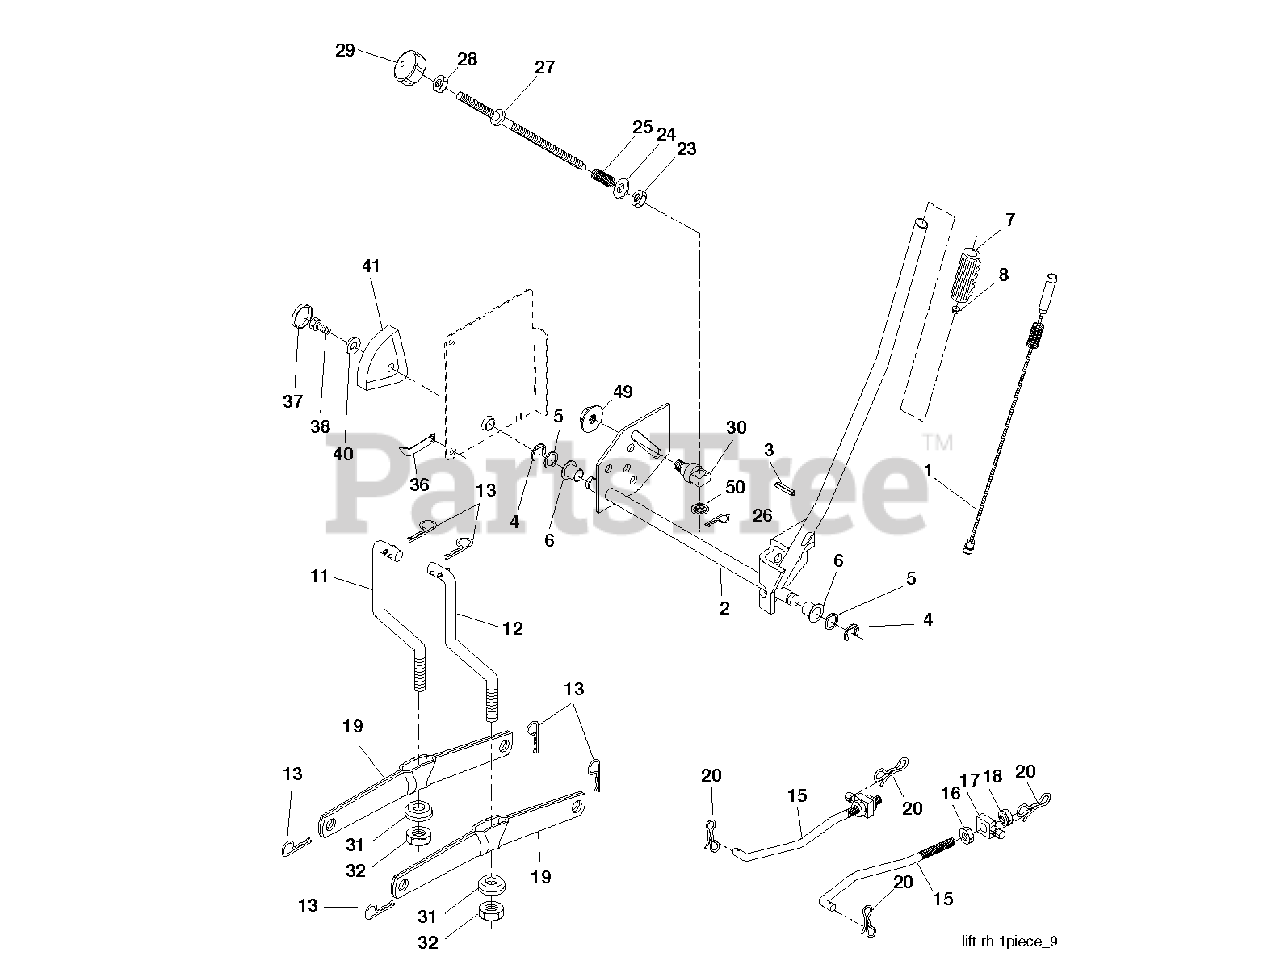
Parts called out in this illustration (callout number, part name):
1	PLUNGER.ASM.LIFT.LEVER.BLK.
2	SHAFT.ASM.LIFT.YT
3	PIN.GROOVE.5/16
4	RETAINING RING LT
6	BEARING.NYLON
7	GRIP HANDLE
8	PLUNGER BUT KIT
11	LINK
12	LINK
13	Retainer Spring
15	LINK.SUSPENSION.FRONT
16	NUT.HEX.JAM.1/2-13
18	NUT.LK.W/WSH.1/2.
19	ARM.REAR.SUSPENSION
20	PIN.COTTER.7/16.BOW TI.
23	Special Nut
26	RETAINER CLIP
27	ROD ADJ LIFT
28	NUT
29	KNOB INF 3/8-16
31	BEARING.PIVOT.LIFT
32	NUT CROWNLOCK 3/8-24
36	POINTER, HEIGHT INDICATOR
38	SCREW 5/16-18X1
41	HEIGHT INDICATOR
49	NUT.HEX.FLANGE.3/8-16.LOCKNUT
50	NUT PUSH M
